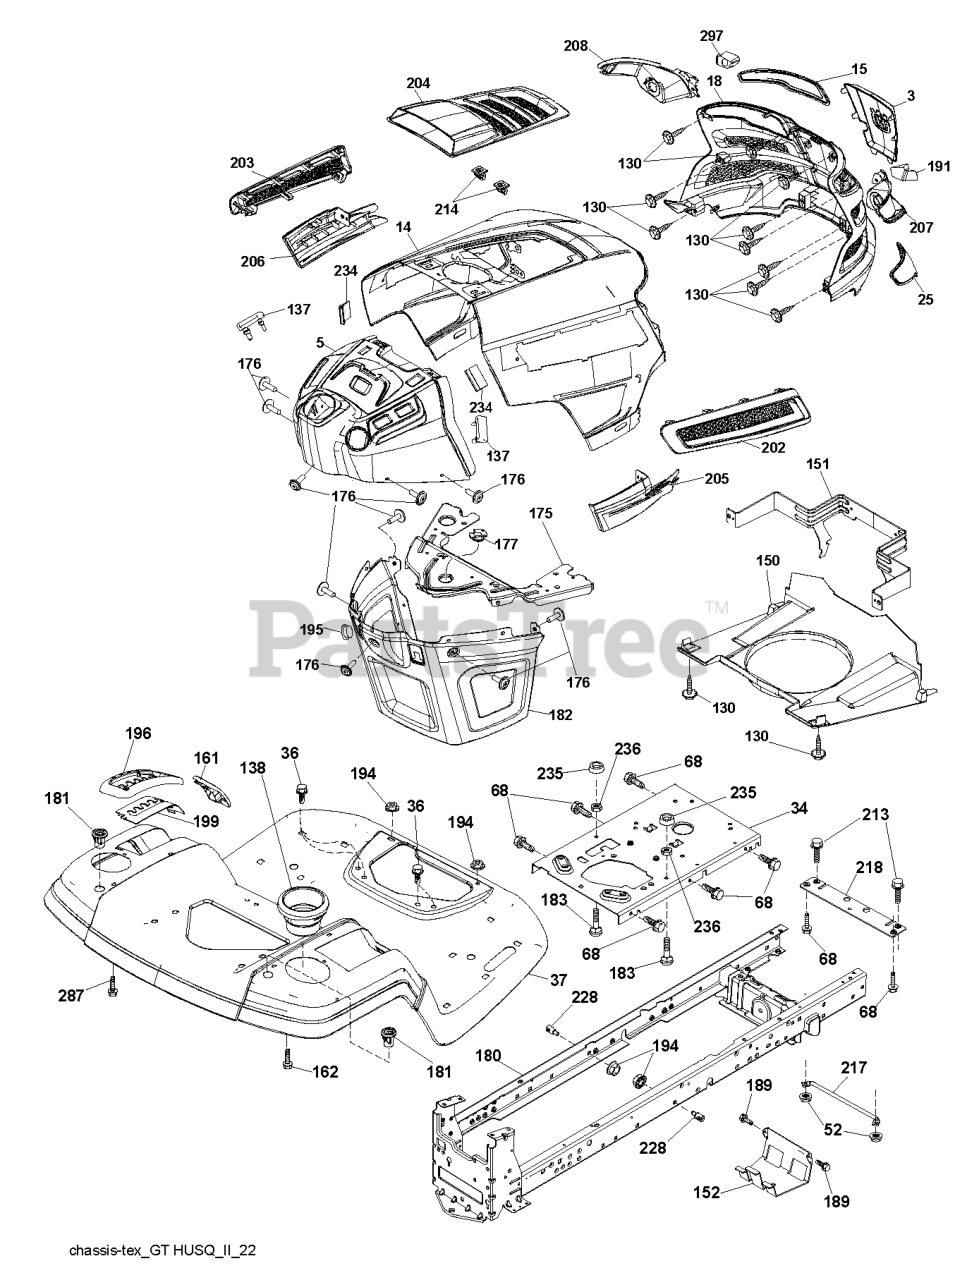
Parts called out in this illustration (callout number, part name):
3	APPLIQUE.SUBASM.GT.HUSQ.II
5	DASH.UPP.GT2.SM.MCLUTCH.CHOK
14	HOOD.ASM.HUSQVARNA.GT.TEX.422
15	LENS.HEADLIGHT.LH.GTII.2011
18	GRILLE.SUBSTRATE.2011.
25	LENS.HEADLIGHT.RH.GTII.2011
34	PLATE.ENGINE.WELDED.CHASSIS
36	SCREW 5/16"
37	FENDER.TLT.W/CPH.W/FW.ORANGE
52	LOCKNUT
68	Screw 5/16-18 x 1/2 Hex, Self Tapping 5/16-18 x 1/2
130	SCREW.#10 X 0.750.BOS
137	BUMPER DASH
138	CUPHOLDER.TL.TEX.418
150	AIR DUCT.GTV2(1.66"RING HEIGHT
151	BRACKET.PIVOT.HOOD.GT.HUSQ.II
152	SHIELD.BROWNING.W/TEX
161	WINDOW.FUEL.LT.HUSQ.TEX.418
162	SCREW.HI-LO.CONSOLE
175	PLATE.CROSSMEMBER.HUSQ
176	SCREW.#10-24X5/8.RN.QU
177	BUSHING, STEERING
180	CHASSIS
181	BUSHING.MNT.FEND.CRGO.
182	DASH.LOWER.COMMON.12V.ADAPTOR
183	BOLT.5/16-18X1-1/4 FULL THD
189	SCREW
191	INSERT.REFLECTIVE.RH.HUSQ.GTII
194	NUT LOCK HEX FLANGE 5/16-18
195	PLUG.HOLE.DASH.LOWER.12V.BLK
196	RP CONSOLE.ASM.DECKLFT.GR/RBT.
199	PLATE.DECK.LIFT.HUSQ.LT
202	VENT.SIDE.RH.GT.HUSQ.II.
203	VENT.SIDE.LH.GT.HUSQ.II.498
204	VENT.TOP.HUSQ.GT2
205	SIDE.TRIM.RH.GT.HUSQ.II
206	SIDE.TRIM.LH.GT.HUSQ.II.GRAY
207	BEZEL LIGHT.RH.GT.II.MYLAR
208	BEZEL LIGHT.LH.GT.II.MYLAR
213	BOLT
214	CLIP.RETAINER.TINNER.
217	ROD.PIVOT.HOOD
218	X-PIECE.HOOD.STOP.NON/
228	STUD.FASTNER.W/ANTI-ROTATE
234	BUMPER.HOOD.TEX.HUSQVARNA
235	SPACER FENDER
236	NUT.CENTERLOCK.5/16-
287	SCREW 1/4X20
297	INSERT.REFLECTIVE.LH.HUSQ.GTII
